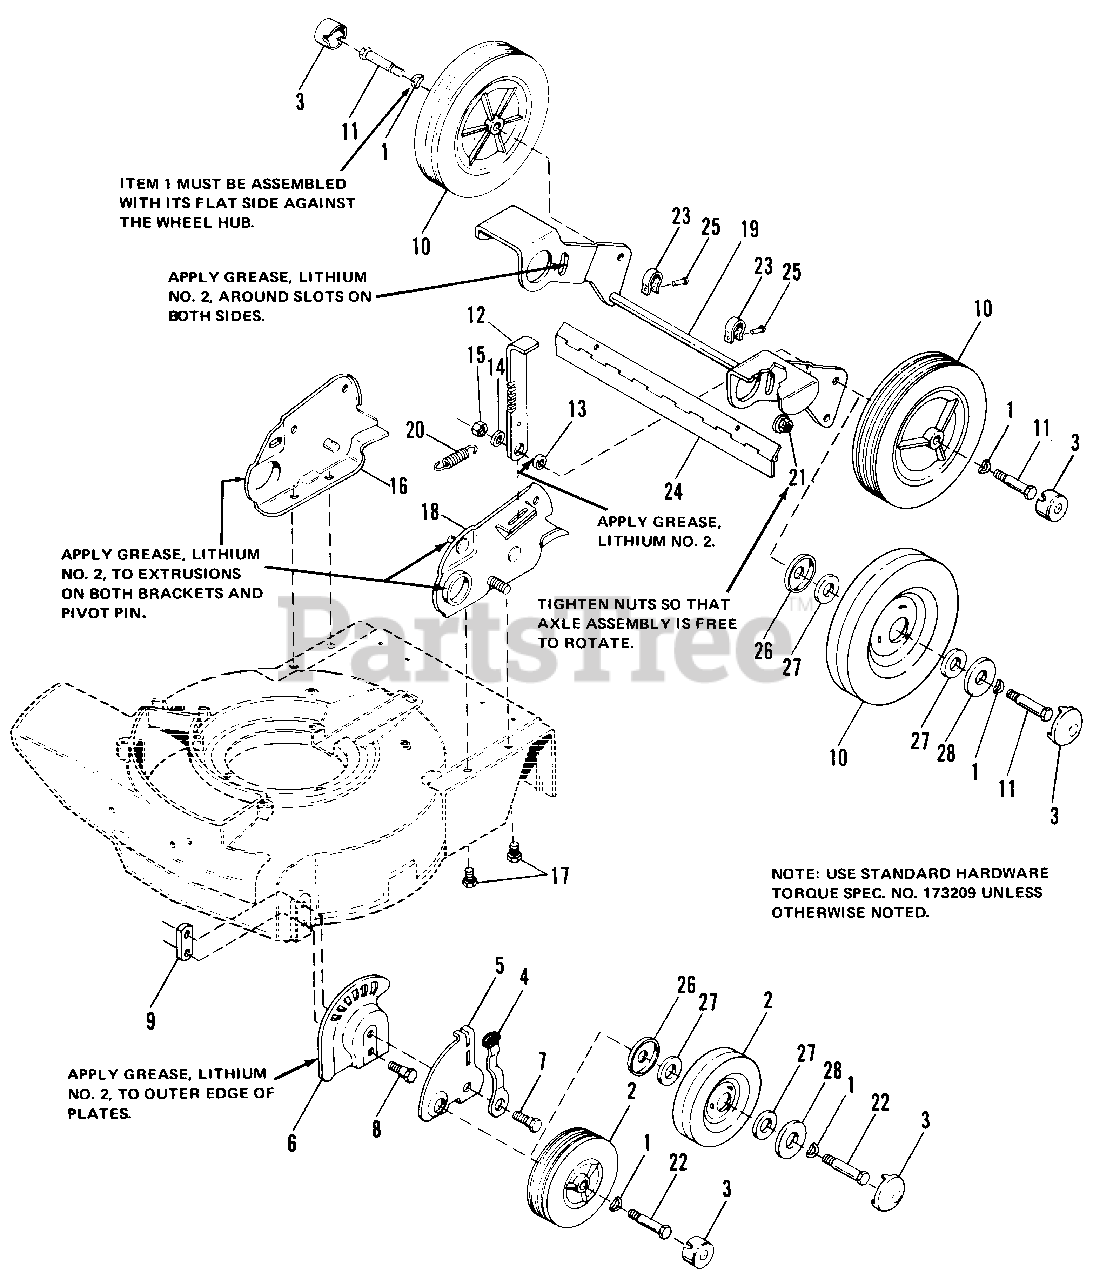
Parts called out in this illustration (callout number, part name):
1	WASHER, Special
2	WHEEL, 6" Front
3	CAP, Hub
4	SPRING, Height Adj.
5	ADJUSTER, Height, Front
6	PLATE, Adjuster
7	BOLT, Shoulder
8	CAPSCREW, Hex, 3/8-16 x 3/4
9	NUT, Pilot Twin
10	WHEEL, 10"
11	BOLT, Wheel
12	ADJUSTER, Height Rear
14	WASHER, Plain, 5/16
15	LOCKNUT, Hex, Full, 5/16-18
16	BRACKET ASSY, R.H.
17	SCREW, Taptite, 1/4-20 x 3/8
18	BRACKET ASSY, L.H.
19	PLATE & TUBE ASSY
21	LOCKNUT, Hex, Flange, 5/16-18
22	BOLT, Front Wheel
24	HINGE, 21" Mower
25	RIVET, Tubular
26	SEAL, Housing
27	SEAL, Wheel
28	SEAL, Housing
